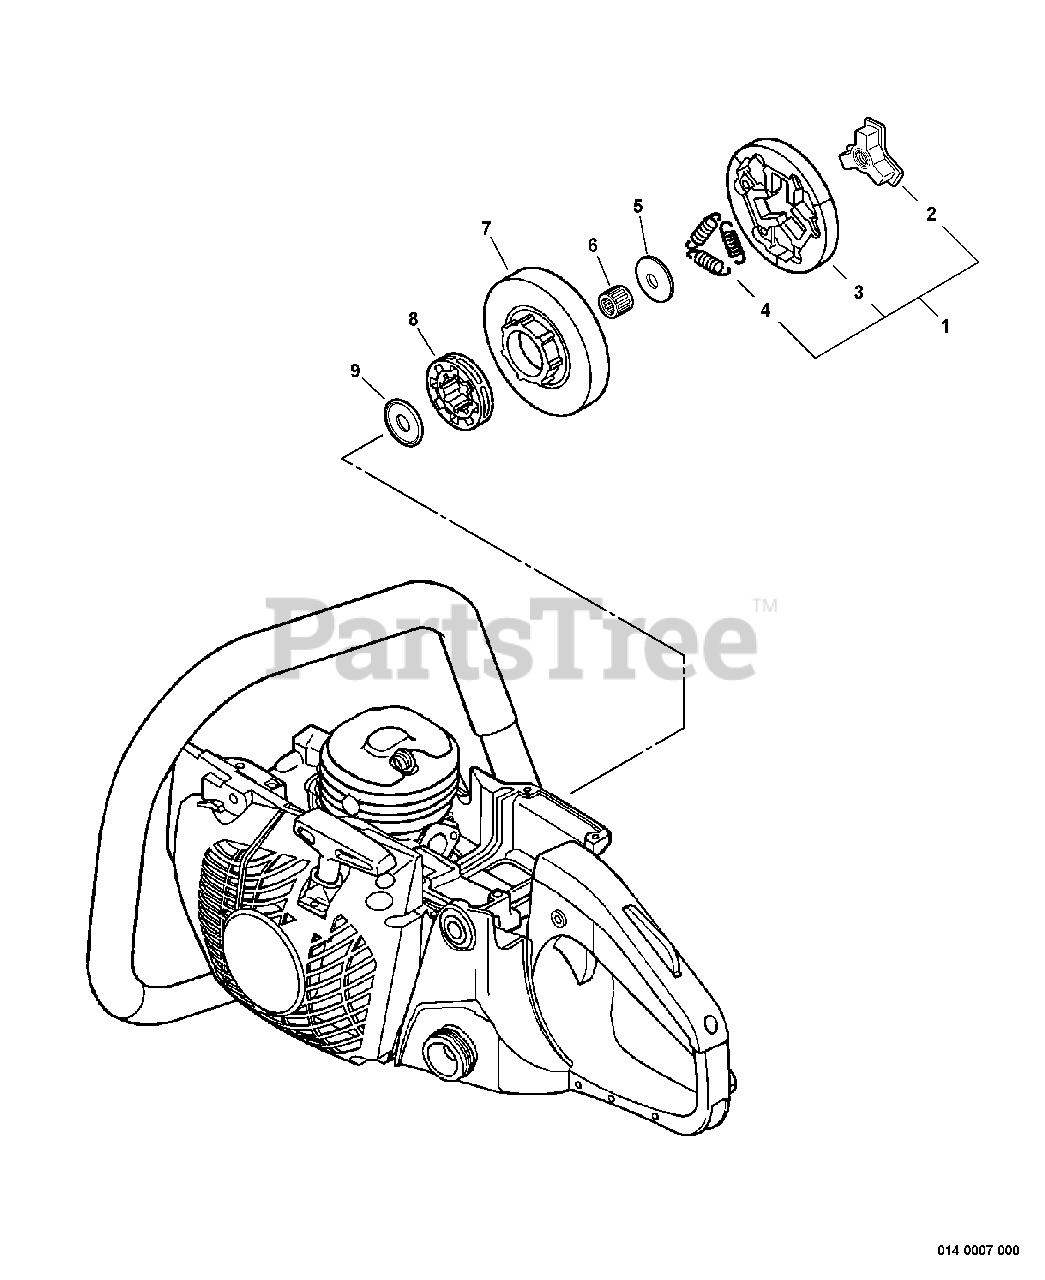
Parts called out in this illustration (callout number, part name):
1	CLUTCH ASSY
2	HUB, CLUTCH
3	SHOE SET, CLUTCH (3PCS)
4	SPRING, TENSION
5	PLATE, CLUTCH
6	BEARING, NEEDLE
7	DRUM, CLUTCH
8	SPROCKET, 0.325 RIM
9	PLATE, CLUTCH
